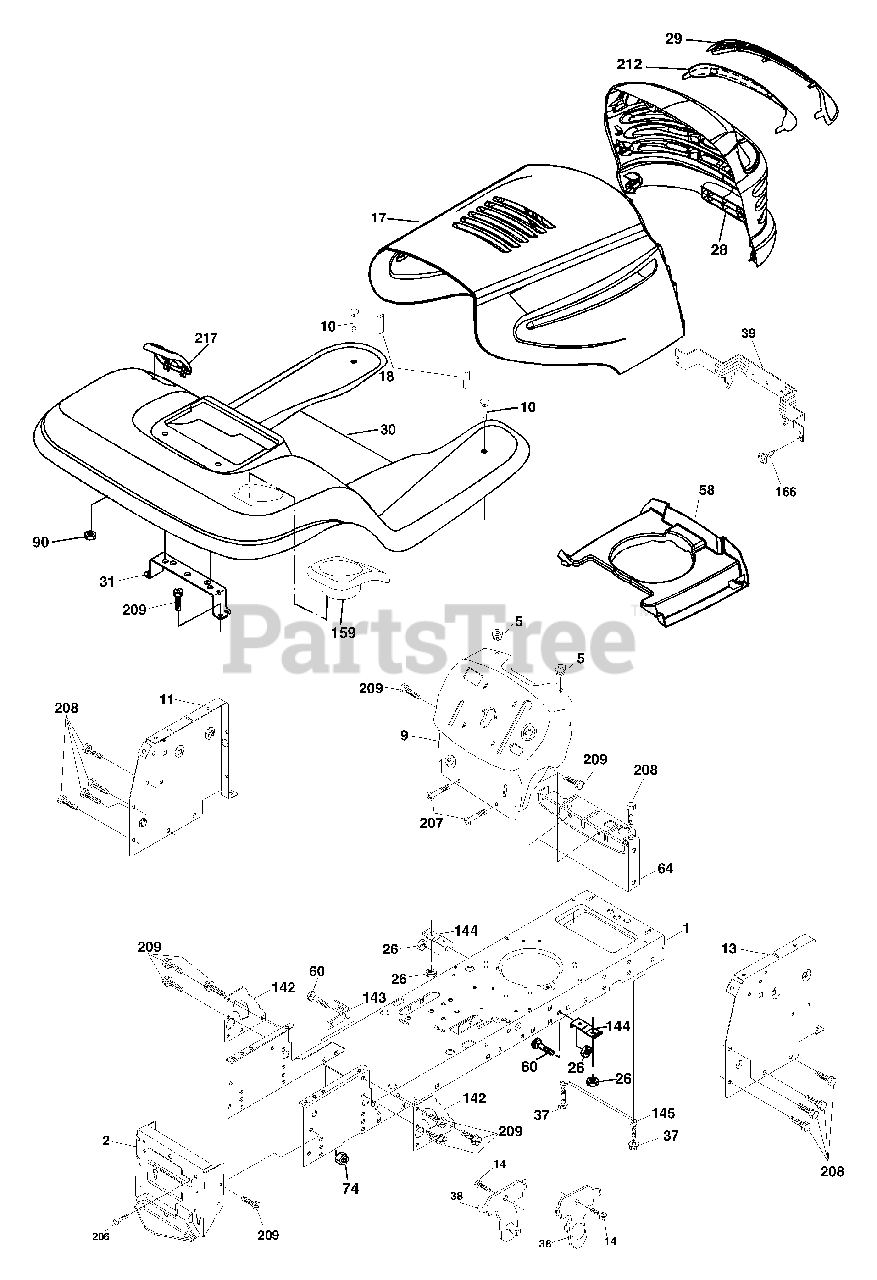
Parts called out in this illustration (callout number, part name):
1	Chassis
2	Drawbar
5	Bumper Hood/Dash
10	Bolt Carriage 3/8-16 x 1
11	Panel Dash Lh
13	Panel Dash Rh
14	Screw Thdrol 3/8-16 x 1/2
17	Hood
18	Bumper Hood
26	Nut Lock Hex W/Ins 3/8-16 unc
28	Grille/Lens Asm
29	Lens Grille
30	Fender Footrest STLT Pnt
31	Bracket Fender
37	Screw Thdrol 6/16-18 x 1/2 TYT
38	Bracket Asm Pivot Mower Rear
39	Bracket Pivot
58	Duct Air
60	Bolt RDHD Sqnk 3/8-16 unc x 3/4
64	Dash Lower STLT
74	Nut Crownlock 3/8-16 unc
90	Nut Self Thd Wsh - HD 1/4 Zinc
142	Plate Reinforcement STLT
143	Bracket Swaybar Chassis
144	Bracket Footrest Step-thru
145	Rod Pivot Chassis/Hood
159	Cupholder
166	Screw 10 x 3/4 Single Lead-Hex
206	Bolt Shoulder 5/16-18
207	Screw Thdrol 5/16-18 x 1/2
208	Screw Thdrol 3/8-16 x 1/2
209	Screw Hexwsh Thdr 3/8-16 x 3/4
212	Insert Lens Refl.
217	Console Fuel Window
